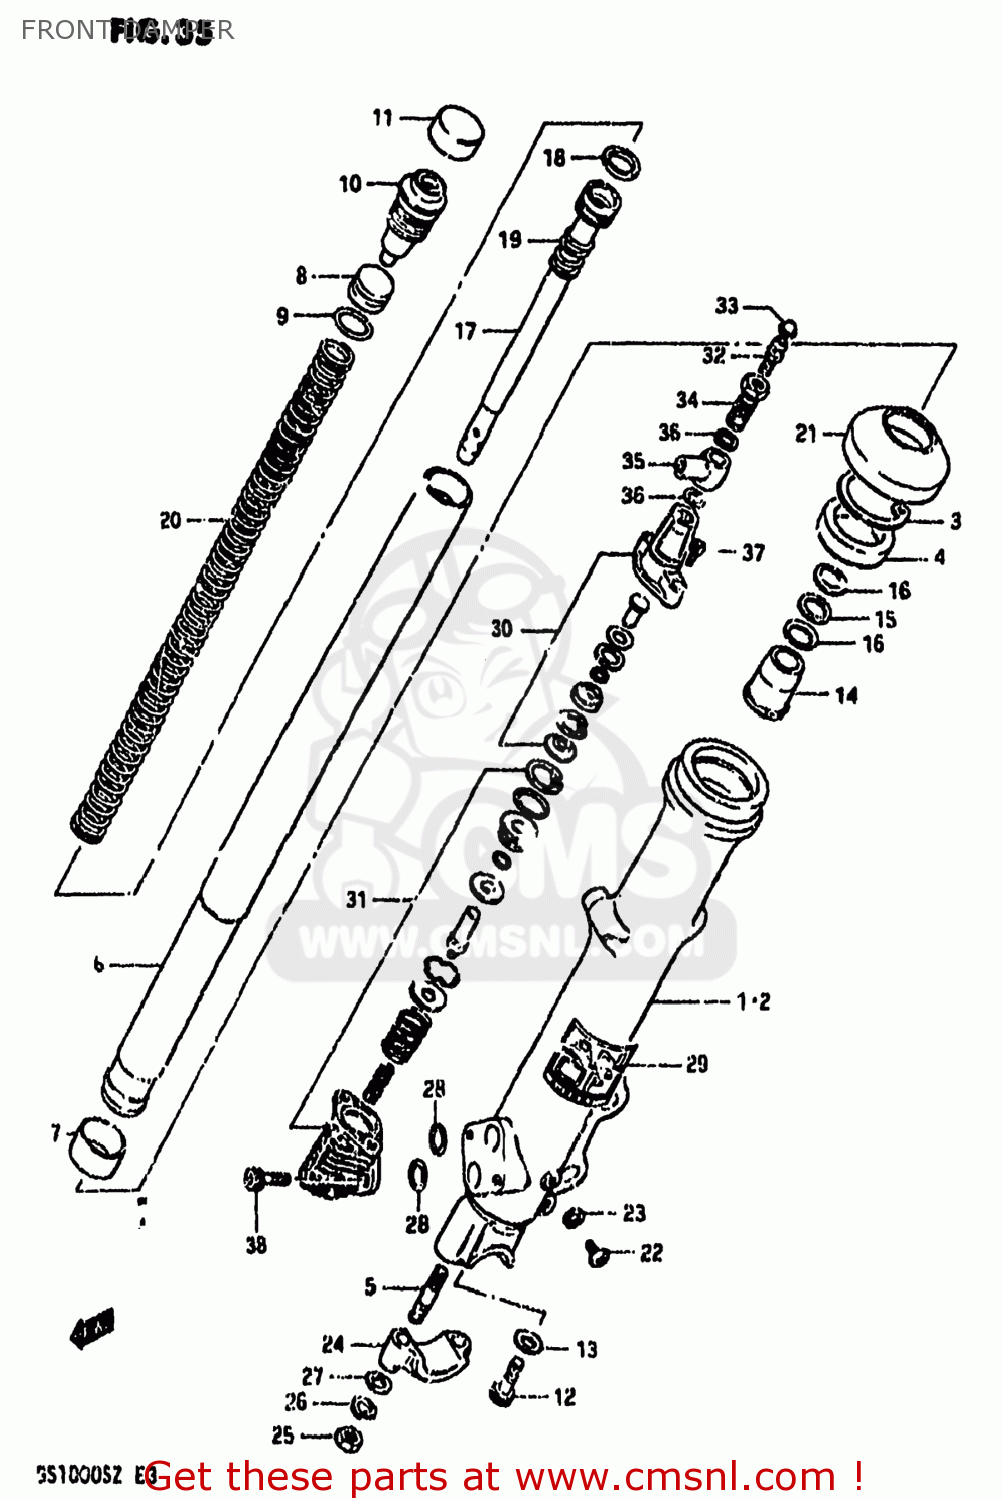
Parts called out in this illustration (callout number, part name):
0	DAMPER ASSY, LH
1	OUTER TUBE, RH
2	OUTER TUBE, LH
3	RING,STOPPER
4	OIL SEAL,FRONT FORK
5	STUD 8X30
6	TUBE,INNER
7	PISTON
8	PISTON,FREE
9	O-RING
10	CAP
11	CAP,RUBBER
12	BOLT,FORK CYLINDER(10X25)
13	GASKET (NAS)
14	PIECE,OIL LOCK
15	WASHER
16	WASHER
17	CYLINDER,FRONT FORK
18	RING,PISTON
19	SPRING,REBOUND
20	SPRING,FRONT FORK
21	SEAL,DUST
22	SCREW
23	GASKET,DRAIN,PLUG (NAS)
24	HOLDER,AXLE
25	NUT (8MM)
26	LOCK WASHER
27	WASHER
28	O RING
29	LABEL
30	MODULATOR PLANGER SET
31	MODULATOR VALVE SET
32	BREATHER,AIR
33	CAP,BREADER
34	BOLT,UNION
35	SPACER,FRONT FORK MODULATOR
36	WASHER
37	BOLT,FR FORK
38	BOLT,FRONT FORK
